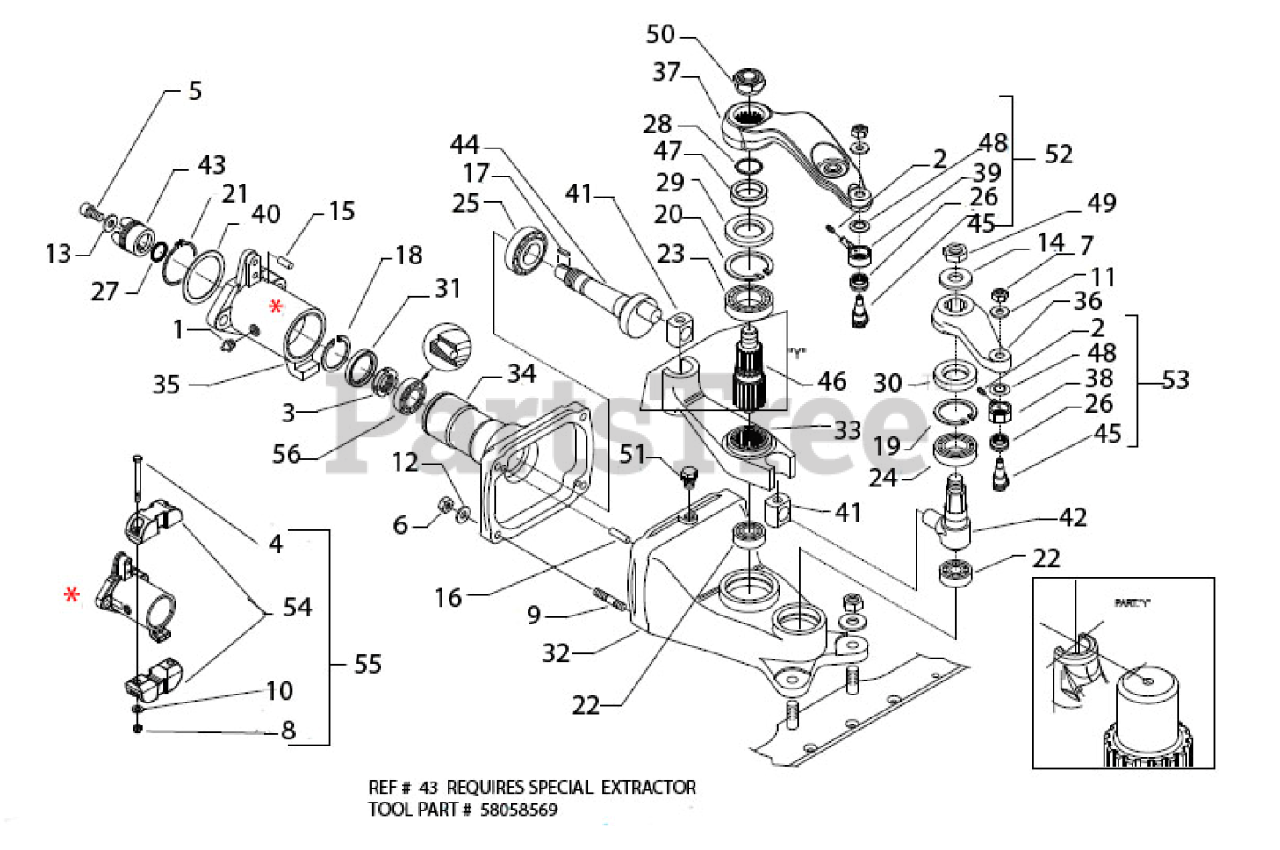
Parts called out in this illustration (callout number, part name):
1	GREASE ZERK
2	GREASE ZERK
3	NUT RING, M25X1.5"
7	SELFLOCK NUT
8	SELFLOCK NUT
16	CYLINDRICAL PLUG
17	KEY, 5X3X15
18	SEEGER RING
19	SEEGER RING
20	SEEGER RING
21	SEEGER RING
25	CYL. ROLLER BEARING
26	BEARING
28	O-RING
29	OIL SEAL
32	BLADE CONTROL BOX
33	INSIDE CRANK
36	CRANK CONTROL LOWER
37	CRANK CONTROL UPPER
38	BLADE SLEEVE, CRANK CONTROL LOWER
39	BLADE SLEEVE, CRANK CONTROL UPPER
40	ADJUSTING RING
42	CONTROL SHAFT
46	SHAFT CONNECTION ROD
49	NUT
50	LOCK NUT
52	UPPER CONTROL DRIVE PIN KIT
53	LOWER CONTROL DRIVE PIN KIT
54	WEIGHT 33 LBS
55	WEIGHT KIT COMPLETE
56	BEARING 32005
